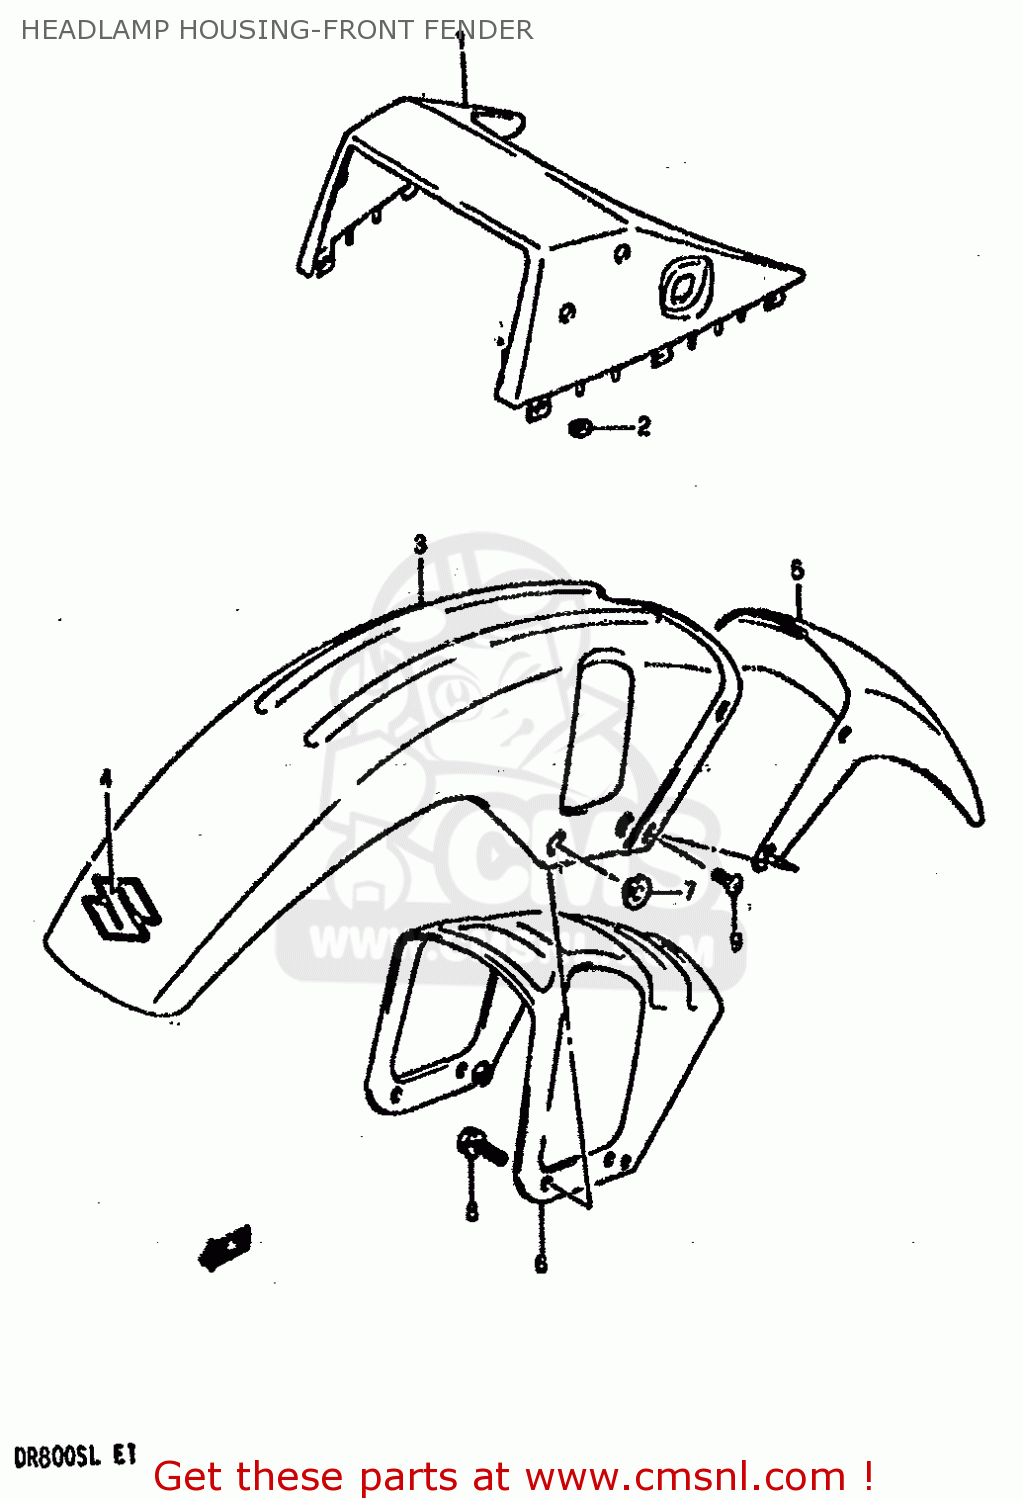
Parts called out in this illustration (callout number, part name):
1	COVER,HEADLAMP (BLACK)
2	NUT
3	FENDER,FR
4	EMBLEM,FRONT FENDER
5	FENDER,FR NO,2
6	BRACE, FENDER
7	WASHER
8	BOLT 6X20
9	SCREW, FRONT & REAR
